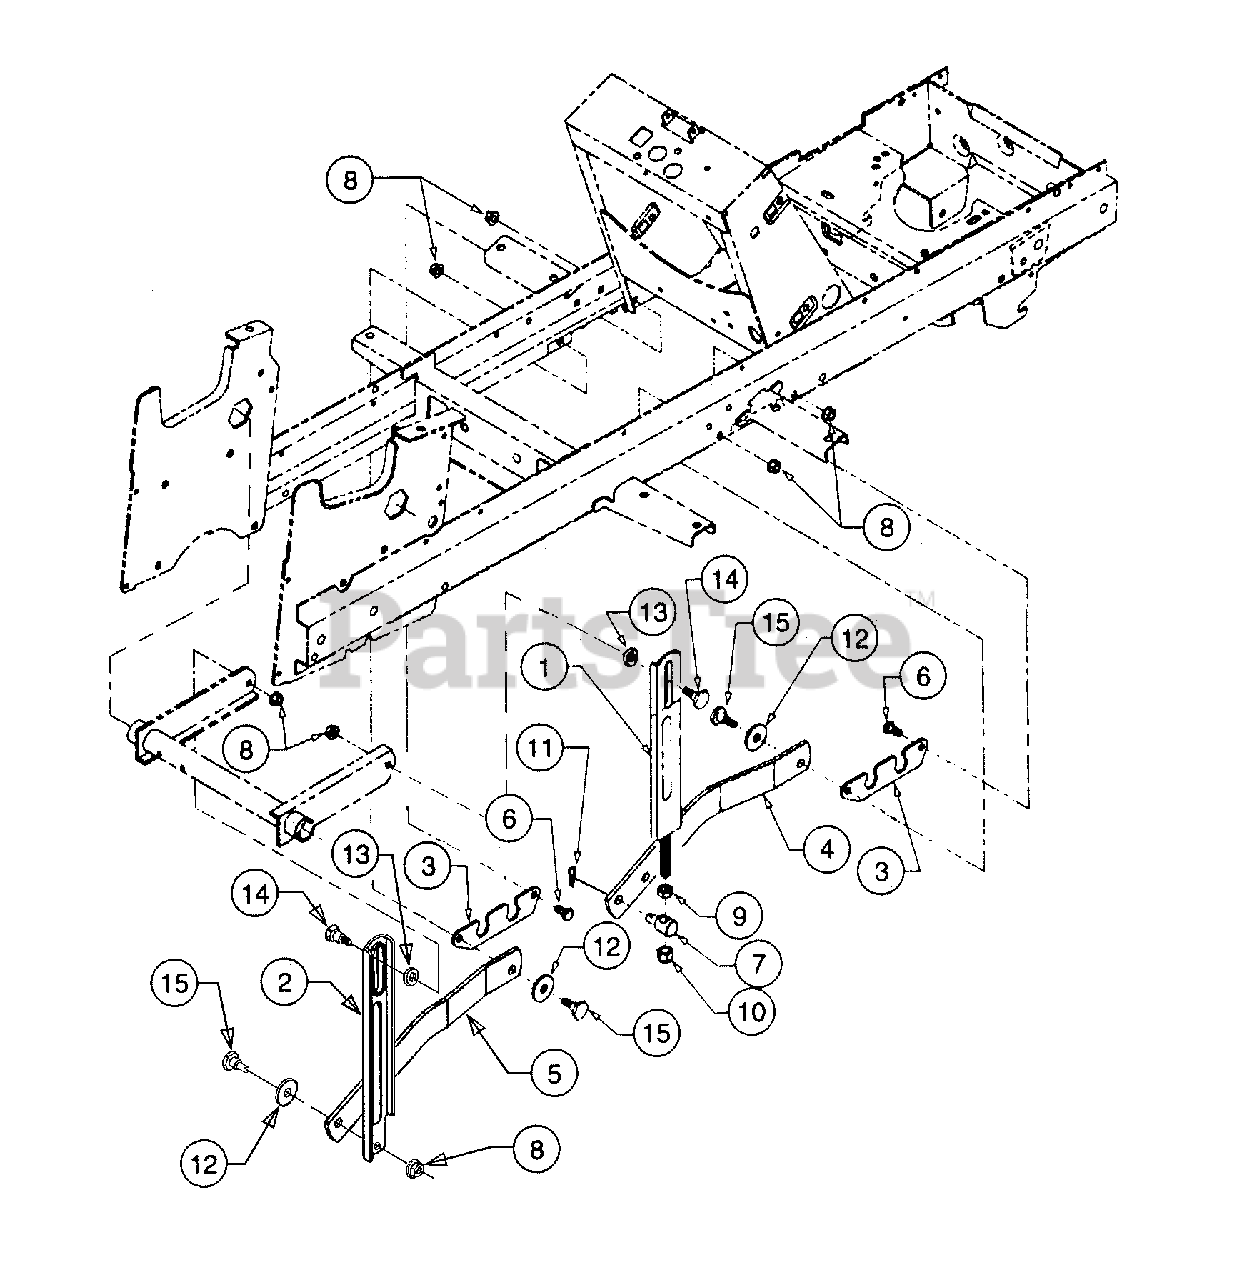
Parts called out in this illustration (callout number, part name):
7	Ferrule, Adjustment
8	Nut, Hex Flange Lock, 3/8-16
9	Nut, Hex Jam, 1/2-13 GR5
10	Nut, Hex Insert Lock, 1/2-13
11	Pin, Internal Cotter
12	Washer, Flat, .5 x 1.5 x .15
13	Washer, Flat, .531 x .875 x .15
14	Bolt, Shoulder
15	Bolt, Shoulder
